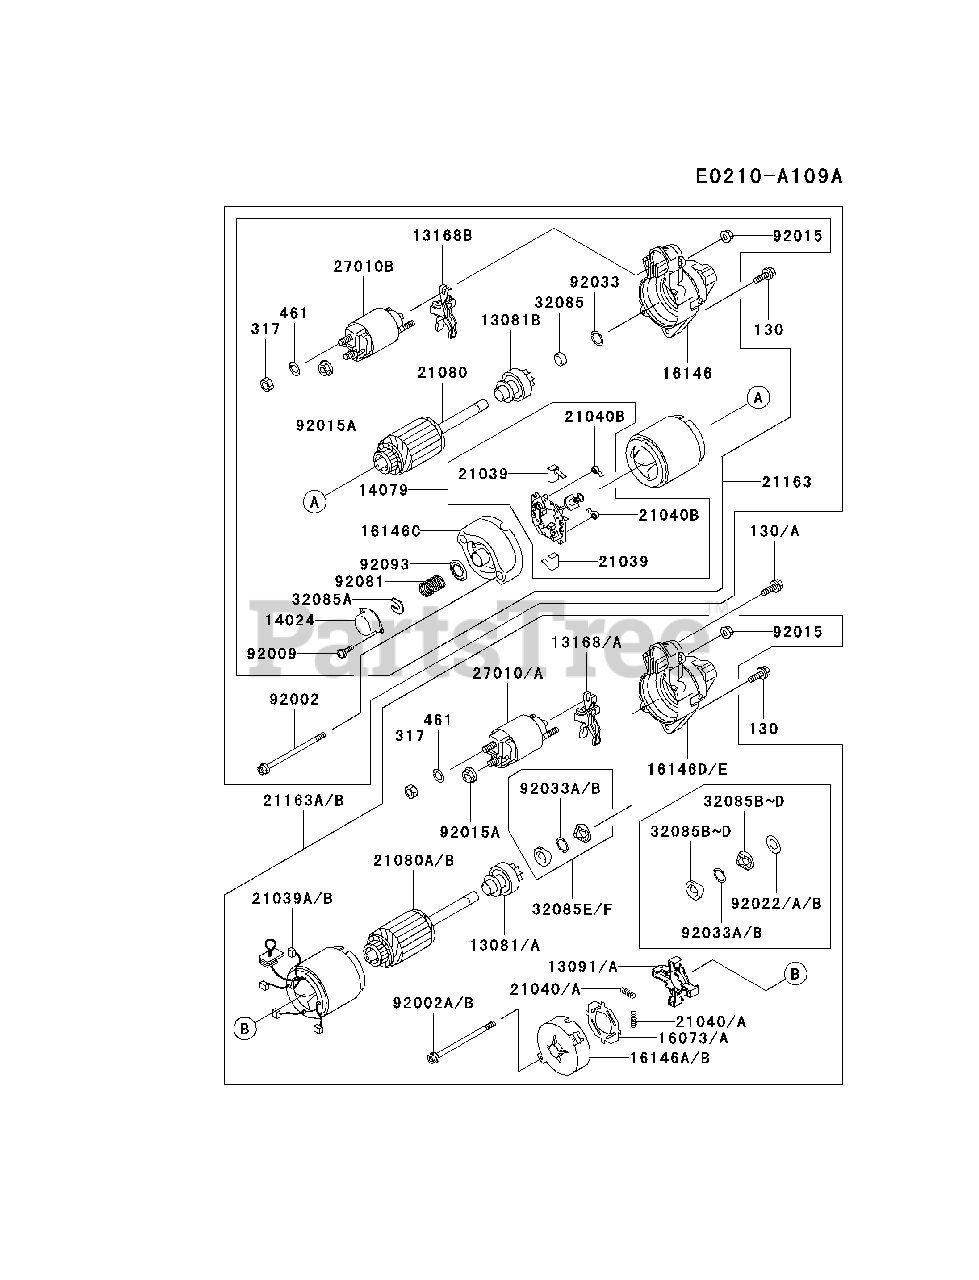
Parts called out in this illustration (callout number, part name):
130	BOLT-FLANGED
130A	BOLT-FLANGED
317	NUT-HEX-SMALL
461	WASHER-SPRING
